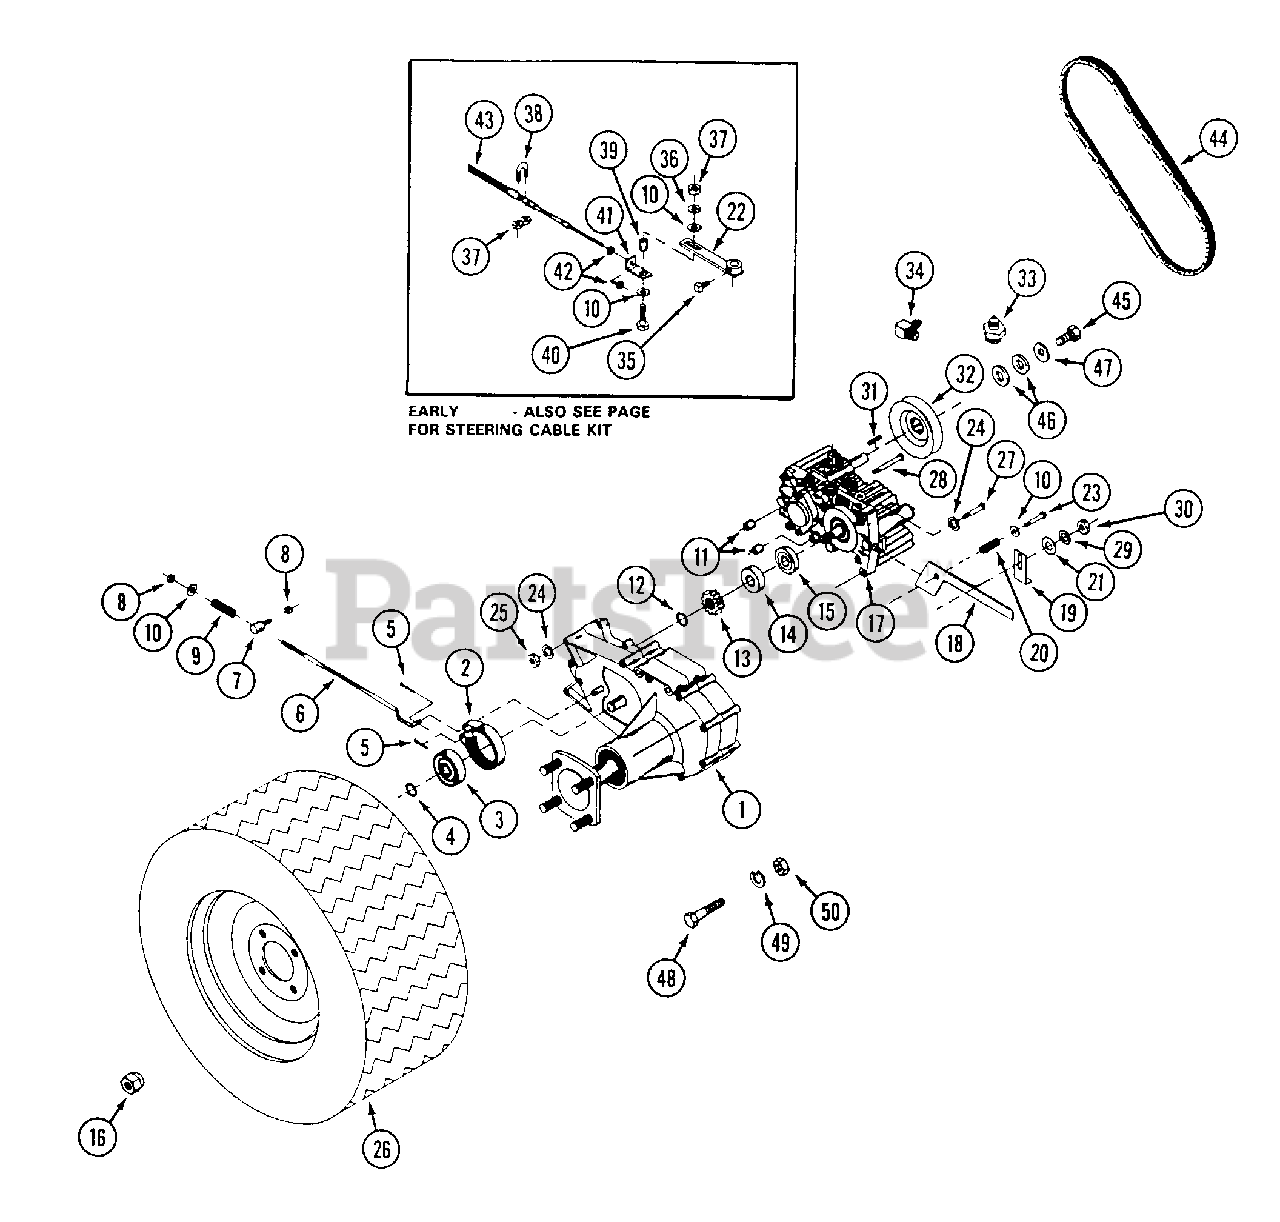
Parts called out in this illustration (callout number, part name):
1	TRANSMISSION - ZT
5	PIN - cotter 1/8" x 1"
7	COLLAR - brake rod
8	NUT - lock 1/4" - 20
10	WASHER - 1/4"
12	RING - snap
14	BEARING
16	NUT - lug 1/2" - 20
17	PUMP - hydro R.H.
18	LEVER - transmission dump
19	BRACKET - dump lever stop
20	SPRING - compression
21	WASHER - 3/8"
22	ARM - transmission
23	BOLT - dump valve
24	LOCKWASHER - 5/16"
25	NUT - 5/16" - 18
26	WHEEL ASSEMBLY
27	BOLT - 5/16" - 18 x 1-3/4"
28	BOLT - 5/16" - 18 x 7-1/2"
29	LOCKWASHER - 3/8"
30	NUT - 3/8" - 16
31	KEY-5 x 5 x 25 mm
32	PULLEY - 4" O.D. x 15 mm ID
34	ADAPTER - 90°
35	SCREW - set 5/16" - 18 x 1/2" square head
36	LOCKWASHER - 1/4"
37	NUT - 1/4" - 20
38	CLAMP - cable
39	BUSHING - cable
40	BOLT - 1/4" - 20 x 1"
41	BRACKET - cable end
42	NUT - lock #10 - 32
43	CABLE - steering 58"
44	BELT - pump drive
45	BOLT - M6 - 1.0 x 12m flange
46	WASHER - .625" x 1"
47	WASHER - .312" x .875"
48	BOLT - 3/8" - 16 x 3-1/2" mounting
49	LOCKWASHER - 3/8"
50	NUT - 3/8" - 16
